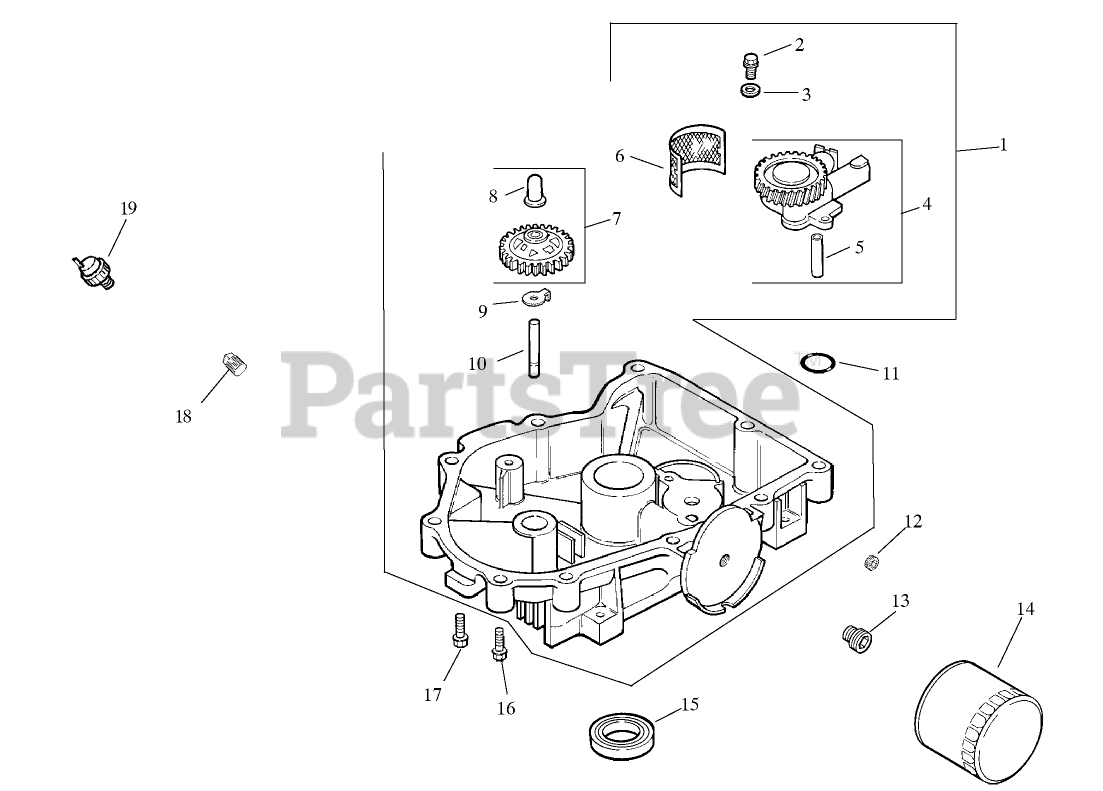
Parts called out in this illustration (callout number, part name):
1	Pan, oil assembly (Includes 2-10)
2	SCREW-FLANGE, THREAD FORMING (M6X1.0X25)
3	WASHER-FLAT (6 MM)
4	Oil pump assembly (Includes 5)
5	Tube, oil pickup
6	Screen-oil
7	Kit, governor gear w/pin (Includes 8)
8	PIN-REGULATING, GOVERNOR
9	Tab-Locking
10	SHAFT-GEAR, GOVERNOR
11	O-Ring
12	Plug-pipe, HH (3/8)
13	Nipple-Filter, Oil
14	Filter-Oil
15	SEAL-OIL (P-T-O END)
16	SCREW-FLANGE (M8X1.25X45)
17	Screw-HF (M8x1.25x45)
18	PLUG-PIPE, SQ HD (3/8)
19	SWITCH-PRESSURE, OIL
